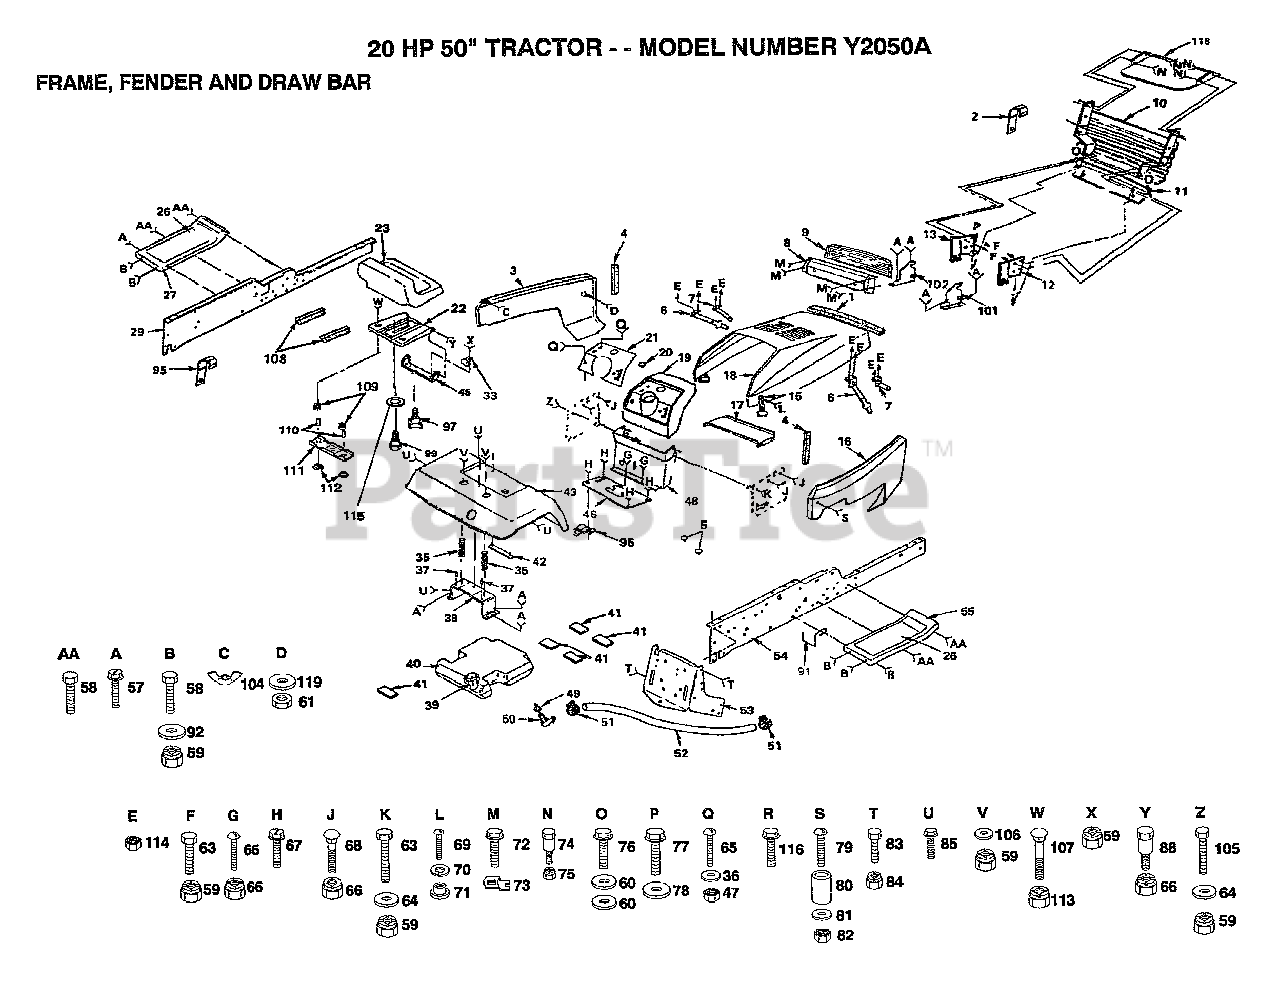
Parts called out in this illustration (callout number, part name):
1	FOAM STRIP T
4	FOAM STRIP T
5	CAP SPRING
9	LENS LT
12	SUPPORT RH YTH
13	SUPPORT LH YTH
15	HOOD LATCH T
16	"PANEL,SIDE RH "
20	PLUG-DASH T
26	FOOTREST PAD
33	CLIP T
35	SPRING COMPRESSIO
36	WASHER
37	NUT-PUSH YT
41	PAD-SPACER LT
43	FENDER
46	CVR GATE SHIFT
48	DASH ASSEMBLY
49	BUSHING OUTLET T
50	FUEL TANK STEM GT
51	HOSE CLAMP
57	SCREW
60	WASHER PM
63	BOLT
64	WASHER
65	SCREW
67	SCREW
68	BOLT
69	SCREW
70	LOCKWASHER
71	WELDNUT
73	"""J"" FASTENER LT"
76	SCREW
77	SCREW
78	WASHER
79	SCREW
80	SPACER LT
81	WASHER
83	BOLT
84	NUT GTV
85	SCREW LT
91	BELT RETAINER GT
92	WASHER
97	"KNOB 1/2"" YT"
99	"BOLT,SHOULDER"
101	SUPPORT RH YTH
102	SUPPORT LH YTH
106	WASHER
108	STRIP FORM
109	SPRING COMPRESSED
110	SPACER SPLIT
111	BRKT SWITCH
112	BUSHING
114	NUT
115	WASHER
116	SCREW GTV
118	"SHIELD,HEAT"
